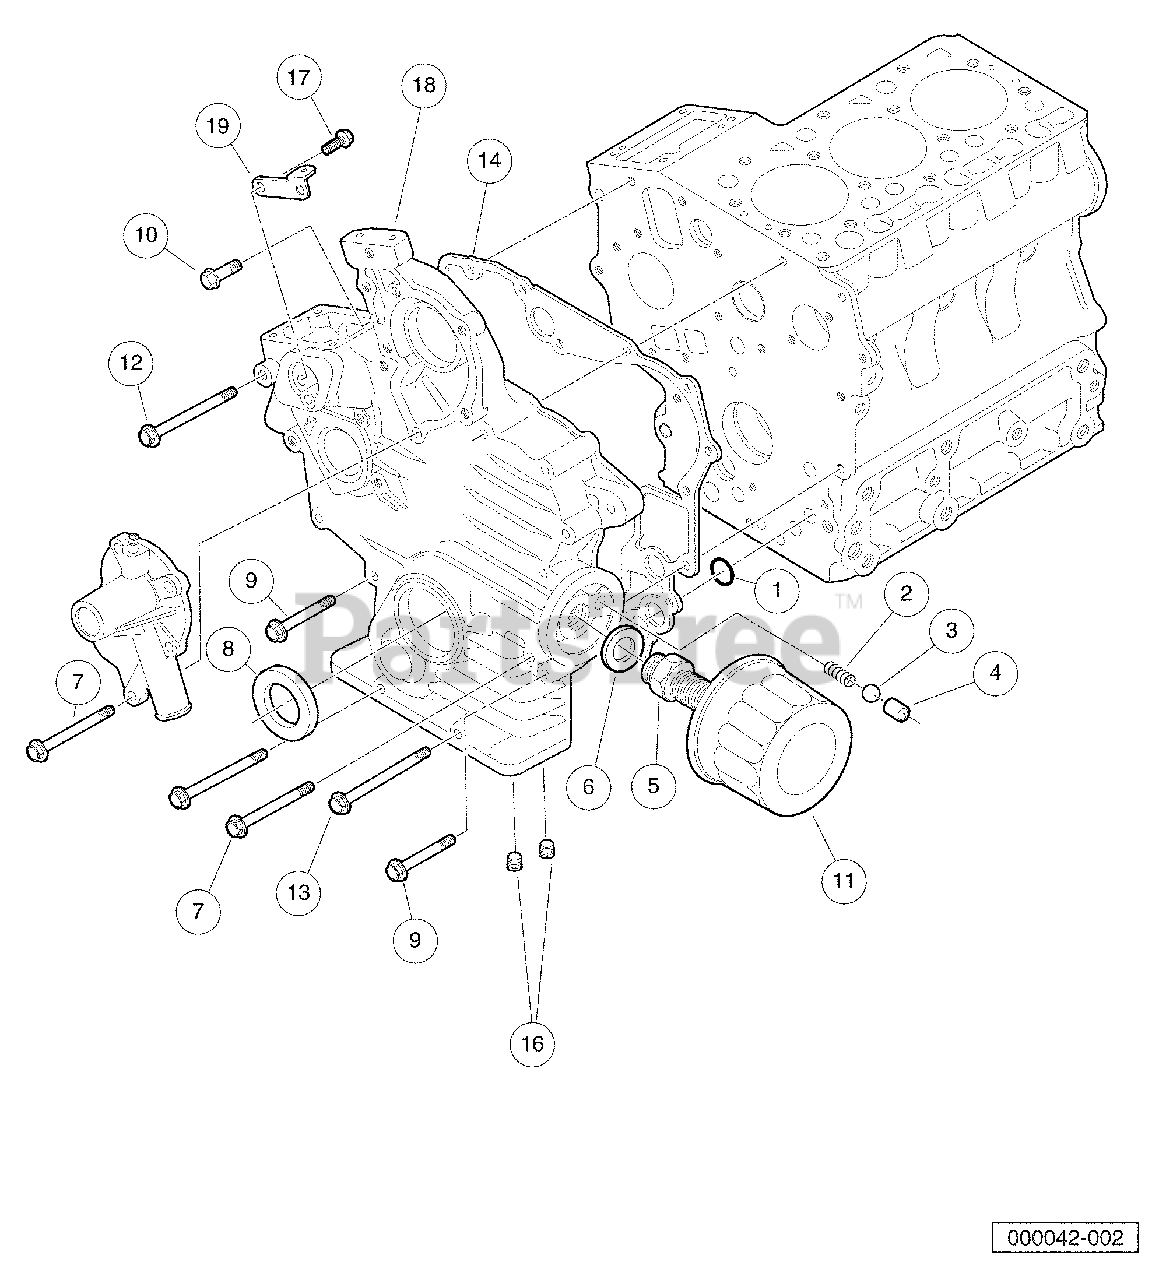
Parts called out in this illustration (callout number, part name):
1	O Ring, 18 X 13
2	Spring, Valve
3	Ball, Valve
4	Seat, Valve
5	Joint, Pipe
6	Washer, Plain, Special
7	Bolt, M6 X 1 X 60
9	Bolt, D722, Front Case
10	Bolt, D722 Intake Manfld Lower.
11	Filter, Engine Oil, D722
12	Bolt, Gearcase, Top
13	Bolt, Gearcase, Lower.
14	Gasket, Gearcase, D722
15	Case, Gear
16	Plug, 1/4"
17	Screw, Breather.
18	Case, Gear.
19	Stay, Spring
